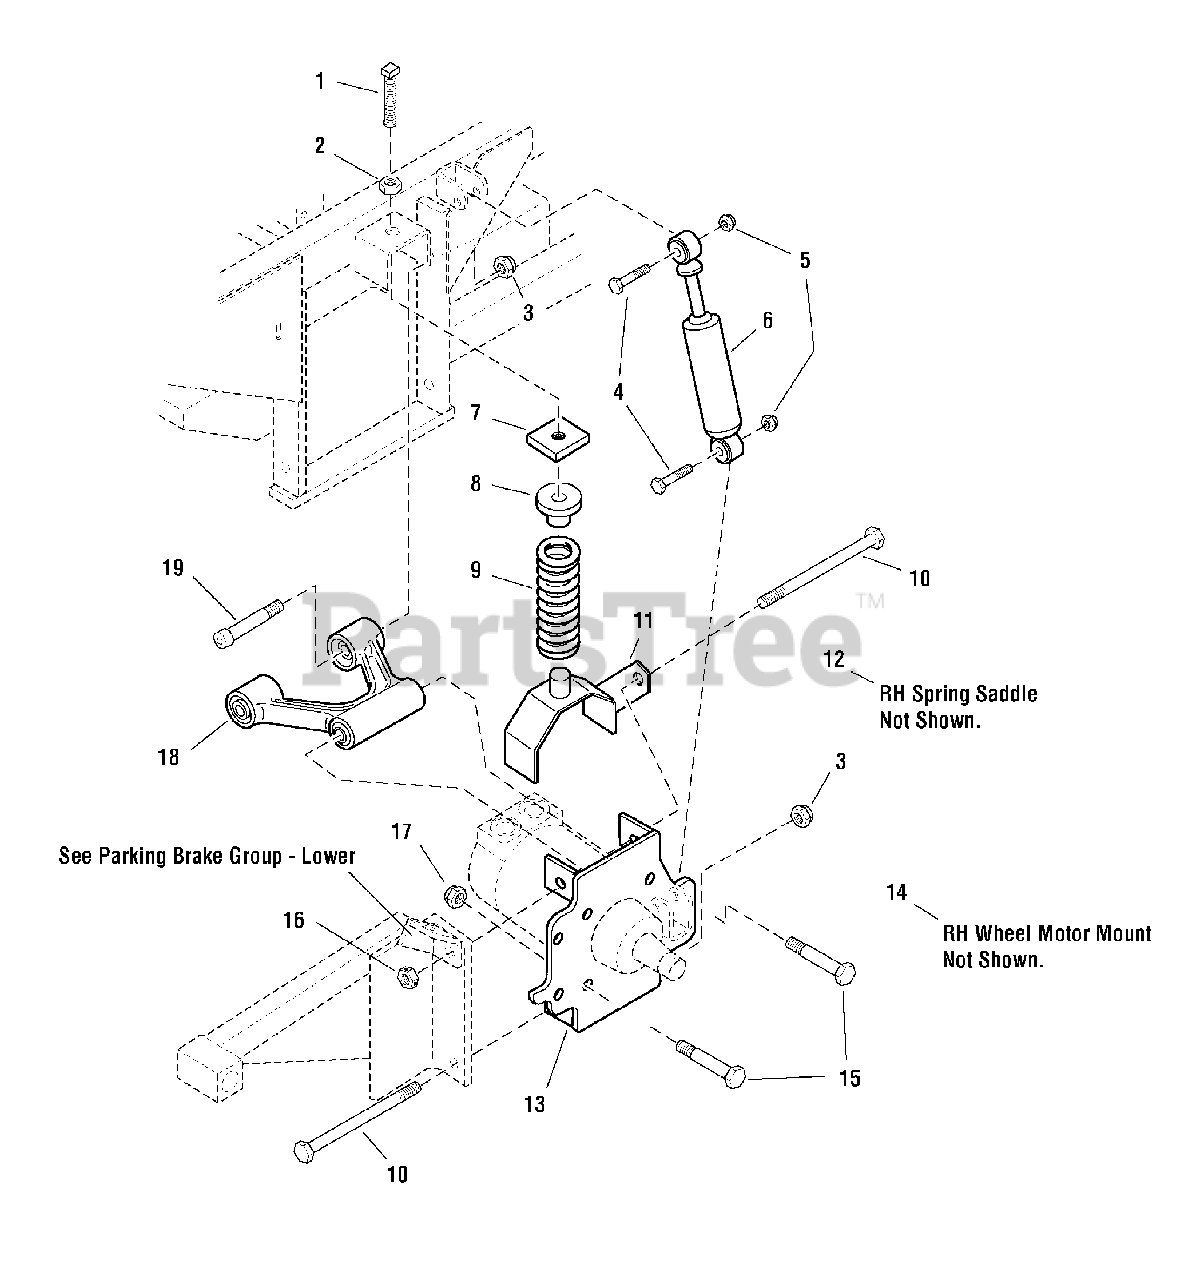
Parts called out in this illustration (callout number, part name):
1	SET SCREW, Square Head, 1/2-13 x 3
2	NUT, 1/2-13 Hex Jam
3	NUT, 1/2-13 Hex Nylon Lock
4	BOLT, 3/8-16 x 2
5	NUT, 3/8-16 Hex Nylon Lock
7	SPRING COMPRESSION PLATE
8	SPRING RETAINER
9	SPRING, Compression
10	BOLT, 1/2-13 x 6-1/2
11	SPRING SADDLE-LH
12	SPRING SADDLE-RH
13	WHEEL MOTOR MOUNT - LH
14	WHEEL MOTOR MOUNT - RH
15	BOLT, 1/2-20 x 3
16	NUT, 1/2-13 Hex Side Lock
17	NUT, 1/2-20 Hex Nylon Lock
19	BOLT, Allen Head, 1/2-13 x 3
